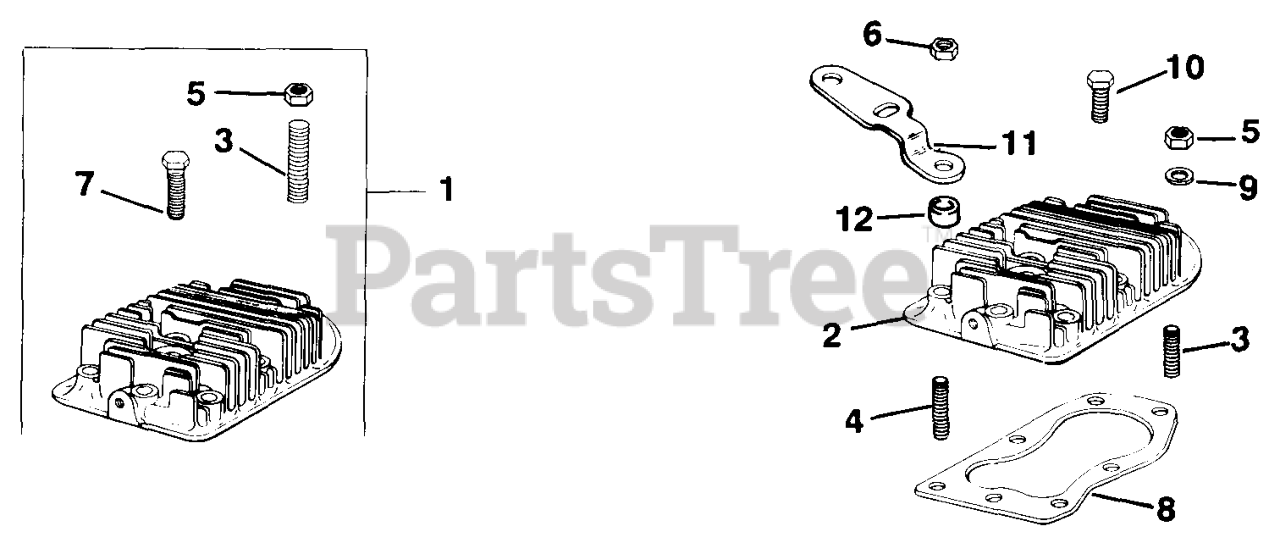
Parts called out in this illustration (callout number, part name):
1	KIT, CYLINDER HEAD - DISCONTINUED
5	NUT, 5/16-18 GRADE 5 USE 25 100 22-S
7	SCREW, SEMS 1/4-20X5/8" USE 25 086 539-S
9	WASHER, FLAT 5/16"
